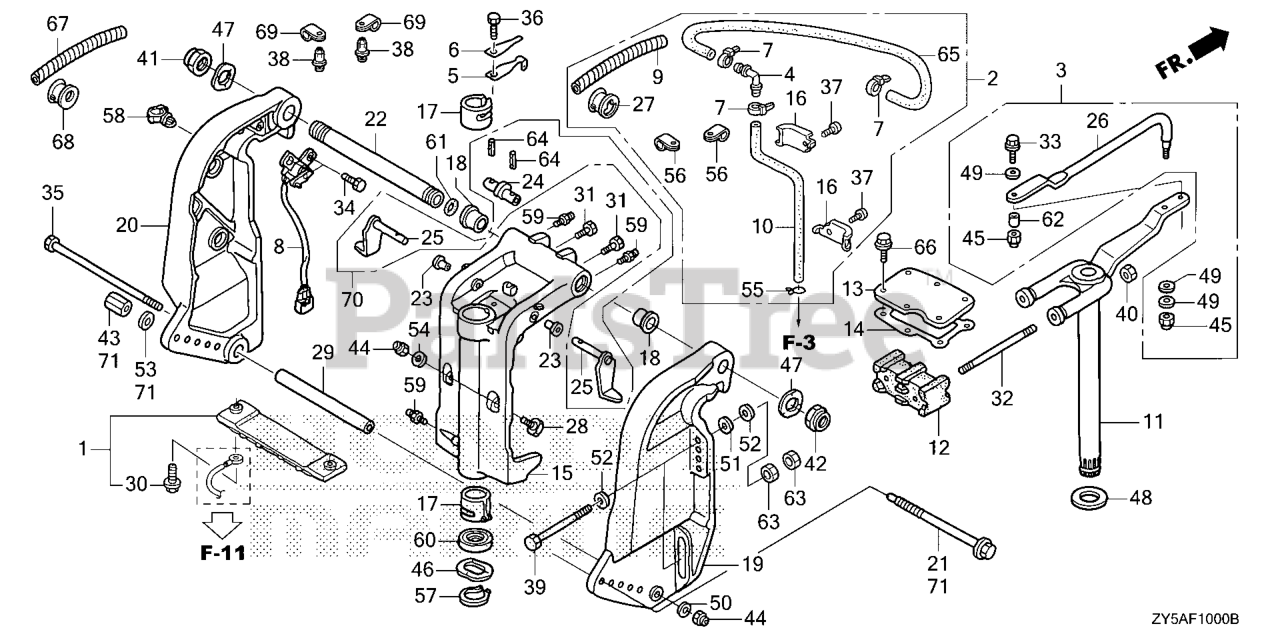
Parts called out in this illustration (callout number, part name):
1	METAL KIT, ANODE Use from Frame SN 4800343.
2	TUBE KIT, SPEED SENSOR
3	ROD KIT, STEERING
4	JOINT A, BREATHER
5	SPRING, CLICK
6	SPRING, CLICK ASSIST
7	BAND, WIRE
8	SENSOR ASSY., TRIM ANGLE
9	TUBE, SPIRAL
10	TUBE, SPEED SENSOR
11	FRAME, MOUNTING
11	FRAME, MOUNT
12	MOUNT, RUBBER (UPPER)
13	HOLDER, MOUNTING (UPPER)
14	GASKET, MOUNTING HOLDER (UPPER)
15	CASE, SWIVEL *NHB14M* (AQUA MARINE SILVER METALLIC)
15	CASE,SWIVEL*NH565*
16	PLATE, SPEED SENSOR TUBE
17	LINER, SWIVEL CASE
18	BUSH, SWIVEL CASE
19	BRACKET, R. STERN *NHB14M* (AQUA MARINE SILVER METALLIC)
19	BRACKET,STE*NH565*
20	BRACKET, L. STERN *NHB14M* (AQUA MARINE SILVER METALLIC)
20	BRACKET,STE*NH565*
21	ROD, ADJUSTING
22	SHAFT, TILTING
23	BUSH, TILT ARM
24	BRACKET, TILTING
25	STOPPER, TILT
26	ROD, STEERING
27	BUSH, MOTOR CODE
28	RECEIVER, THRUST
29	COLLAR, CYLINDER (LOWER)
30	BOLT, FLANGE (6X23) Use from Frame SN 4800343.
31	BOLT (1/4-28UNF)
32	BOLT, STUD (12X145)
33	BOLT (3/8-24UNF)
34	BOLT, FLANGE (6X20) (ENGINE NO.)
35	BOLT, HEX. (10X235)
36	BOLT, HEX. (6X14)
37	SCREW, PAN (6X8)
38	SCREW, RIVET (5X10)
39	BOLT, HEX. (12X130)
39	BOLT, HEX. (12X119)
40	NUT, FLANGE (12MM)
41	NUT, SELF-LOCK (7/8-14UNF)
42	NUT, SELF-LOCK (M25X2.0)
43	NUT, ADJUSTER ROD
44	NUT, FLANGE (10MM)
45	NUT, SELF-LOCK (3/8-24UNF)
46	WASHER, WAVE (40MM)
47	WASHER, WAVE (26MM)
48	WASHER, THRUST (34MM)
49	WASHER (10MM)
50	WASHER, PLAIN (10MM)
51	WASHER, PLAIN (12MM)
52	WASHER, PLAIN (12MM)
53	WASHER, PLAIN (12MM)
54	WASHER, PLAIN (10MM)
55	CLIP, TUBE (B8)
56	CLIP (14MM)
57	CIRCLIP (OUTER) (39MM)
58	CLIP, WIRE HARNESS
59	NIPPLE, GREASE
60	OIL SEAL (39.5X52X6) (ARAI)
61	O-RING (15.54X2.26)
62	COLLAR, STEERING ROD
63	NUT, HEX. (12MM)
64	PIN, SPRING (2.5X20)
65	BULK HOSE, VACUUM (5X3000) (5X250)
66	BOLT, FLANGE (8X35)
67	TUBE, SPIRAL
68	BUSH, MOTOR CODE
69	CLIP (10.7MM)
70	STOPPER KIT, TILT
71	ROD, ADJUSTING
